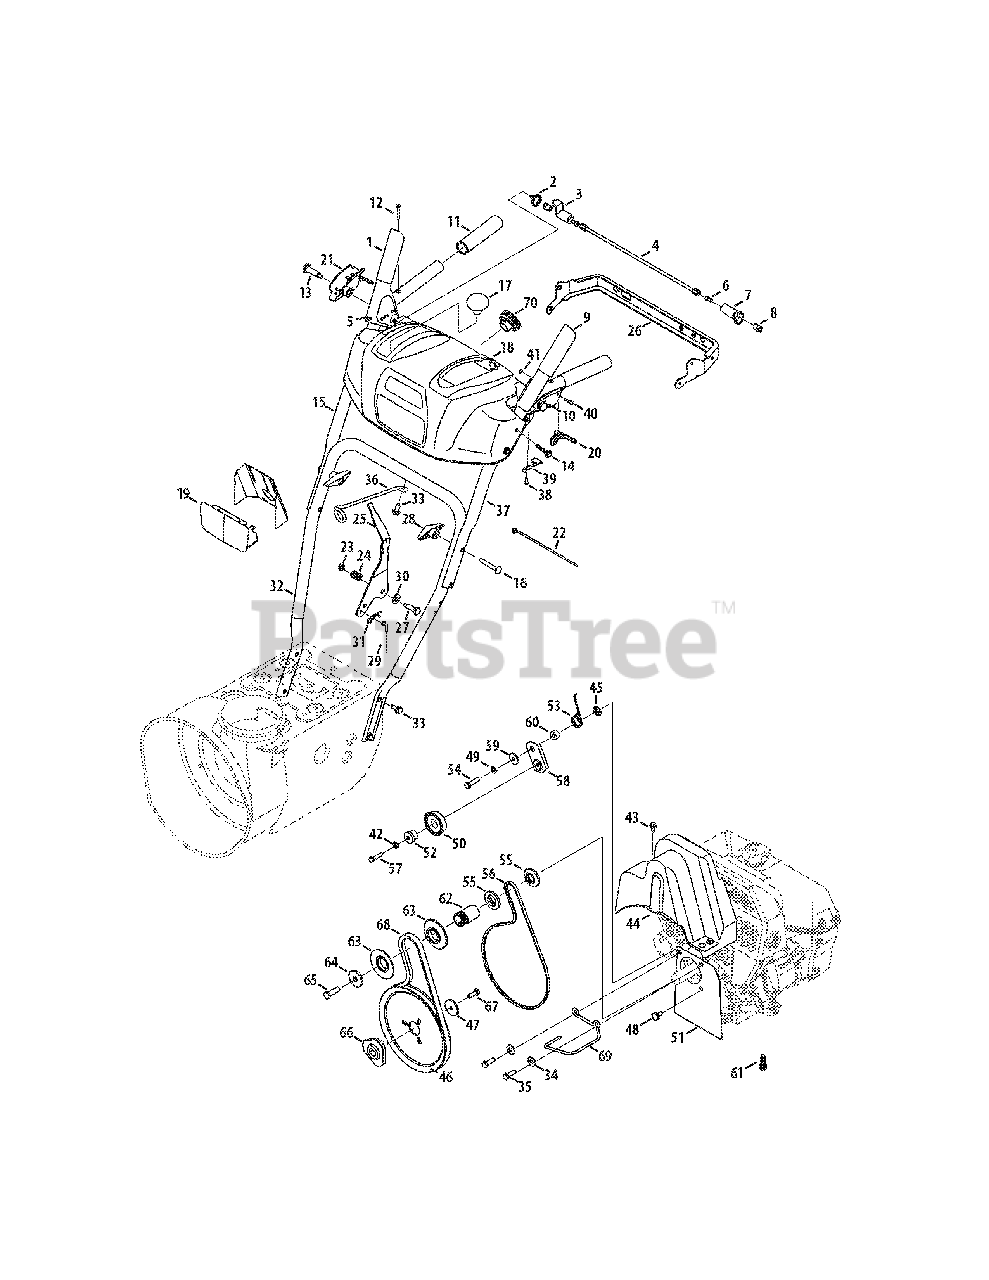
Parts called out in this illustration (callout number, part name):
1	Handle Engagement Ass’y RH
2	Torsion Spring
3	Lock Plate
4	Pivot Rod
5	Rubber Bumper
6	Screw, 1/4-20 x .500
7	Clutch Lock Cam
8	Shoulder Nut, 1/4-20
9	Handle Engagement Assembly LH
10	Handle Clutch Lock LH Assembly
11	Handle Grip
12	Screw, #10-24 x 0.375
13	Shoulder Screw, 1/4-20
14	Screw, 1/4-20 x 1.625
15	Upper Handle RH
16	Carriage Screw, 5/16-18 x 2.25
17	Shift Knob
18	Handle Panel
20	Steering Control
21	Handle Clutch Lock RH Assembly
22	Cable Tie
23	Flange Lock Nut, 1/4-20
24	Compression Spring
25	Shift Lever
26	Panel Bracket
27	Shoulder Screw
28	Wing Knob
29	Speed Selector Cable
30	Flat Washer
31	Click Pin
32	Lower Handle
33	Screw, 5/16-18 x 0.75
34	Flat Washer, .349 x .879 x .063
35	Screw, 5/16-24 x 1.00
36	Cable Guide
37	Upper Handle LH
38	Screw, #8-16 x 0.50
39	Clutch Lock Spring
40	Pin, 3/16
41	Retainer Ring
42	Lock Washer
43	AB Screw, 1/4-20 x 0.625
44	Belt Cover
45	Push-on Nut
46	Auger Pulley
47	Flat Washer
48	Shoulder Screw
49	Lock Washer
50	Idler Pulley Assembly
51	Plt., Cvr.
52	Spacer
53	Torsion Spring
54	Hex Screw, 5/16-24 x 1.25
55	Pulley Half
56	Belt, Wheel Drive
57	TT Screw, 1/4-20 x 1.25
58	Drive Clutch Idler Bracket
59	Shoulder Spacer
61	TT Sems Screw, 3/8-16 x 1.0
62	Spacer
63	Pulley Half
64	Flat Washer
65	Hex Bolt, 3/8-24 x 1.25
66	Pulley Adapter
67	Hex Bolt, 5/16-24 x 0.875
68	V-Belt,.500 x 35.00 Lg
69	Belt Guide
70	Headlight Socket
